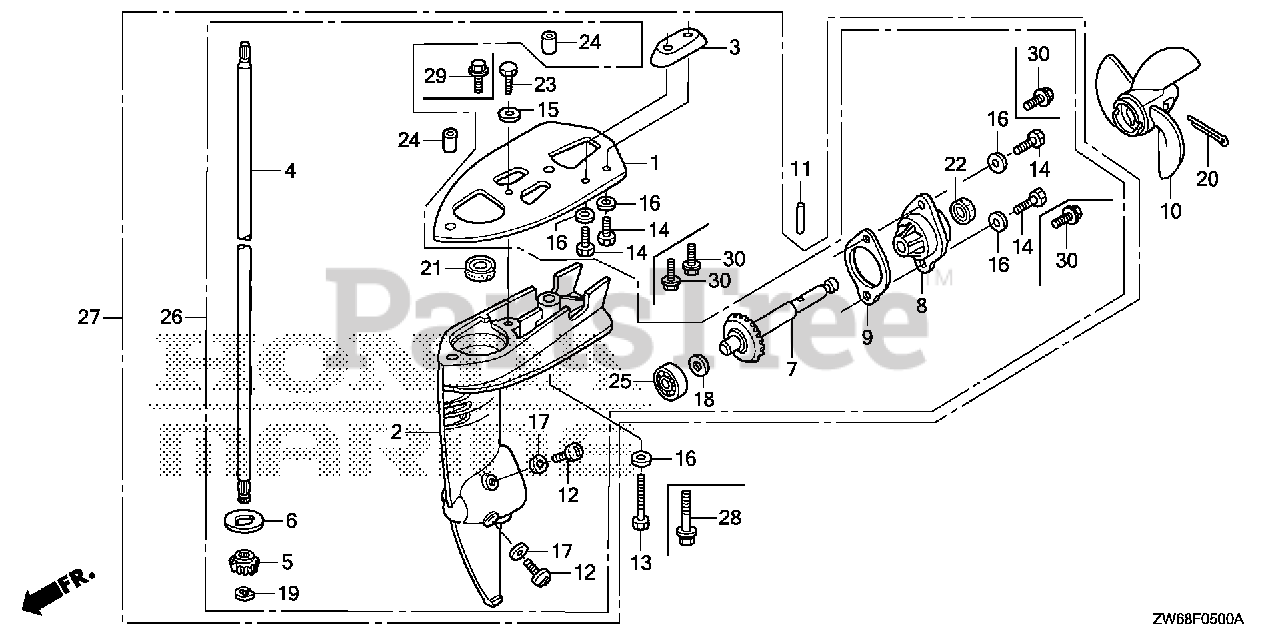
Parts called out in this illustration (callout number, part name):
1	PLATE, CAVITATION *NH246* (LOOSY GRAY)
2	CASE, GEAR *NH246* (LOOSY GRAY)
3	METAL, ANODE
4	SHAFT, VERTICAL (L)
5	GEAR, PINION
6	WASHER, PINION THRUST
7	SHAFT, PROPELLER
8	HOLDER ASSY., PROPELLER SHAFT *NH246* (LOOSY GRAY)
9	GASKET, PROPELLER SHAFT HOLDER
10	PROPELLER, THREE-BLADE *NH283* (STIN GRAY)
11	PIN, SHEAR
12	BOLT, OIL CHECK
12	BOLT, OIL CHECK (8X8)
13	BOLT, HEX. (6X35)
14	BOLT, HEX. (6X16)
15	WASHER, PLAIN (6MM)
16	WASHER, PLAIN (6MM)
17	WASHER, NYLON (8MM)
18	WASHER, GEAR (1.00) (A)
18	WASHER, GEAR (1.05) (B)
18	WASHER, GEAR (1.10) (C)
18	WASHER, GEAR (1.15) (D)
18	WASHER, GEAR (1.20) (E)
19	E-RING (6MM)
20	PIN, SPLIT (3MM)
20	PIN, SPLIT (3.0)
21	SEAL, WATER (11X21X8)
22	SEAL, WATER (11X21X8)
23	BOLT, HEX. (6X12)
24	PIN, DOWEL (8X14)
25	BEARING, RADIAL BALL (6000)
27	CASE ASSY., GEAR *NH246* (L) (LOOSY GRAY)
29	BOLT, FLANGE (6X12)
30	BOLT, FLANGE (6X16) (SUS)
